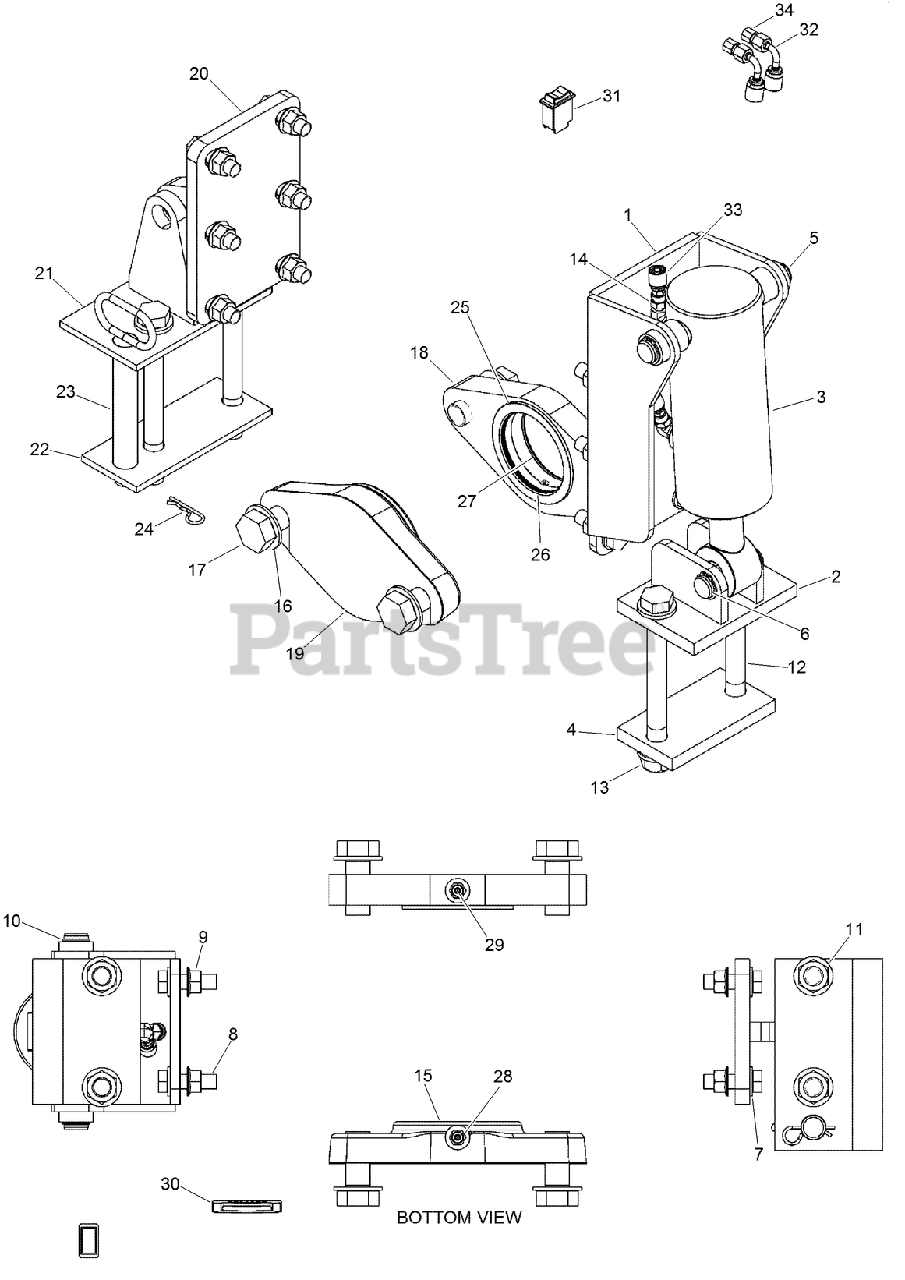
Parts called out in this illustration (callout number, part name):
1	WELDMENT - Cylinder Frame Mount
2	WELDMENT - Rear Axle Mount, Tilt Suspension
3	CYLINDER ASM-102 (4) ID x 152mm (6) stroke, plow swing
4	PLATE - Mounting
5	PIN-PLOW
6	PIN-CLEVIS
9	NUT-HEX FLANGE
10	RING-RETAINING
12	SCREW-HH
14	ELBOW-90 Adj 37FL, 3/8 x 1/2 Tube
15	TRUNION - Axle Pivot, Front
17	BOLT - Hex Hd 1.25 x 3.00 GR8 Pln
18	TRUNION - Axle Pivot, Rear
19	SHIM-MOUNT, AXLE
20	FRAME - Lockout Weldment
21	AXLE - Lockout Weldment
22	PLATE - Mounting
24	PIN-Hair
25	WASHER-THRUST
26	BUSHING-PIVOT
28	ADAPTER-LOCATING
29	FITTING - STR Grease 3/16
30	METER-SLOPE
31	SWITCH-ROCKER, 2 POLE
32	HOSE - Hydraulic
33	HOSE - Hydraulic
34	ORIFICE - 0.047 Inline
